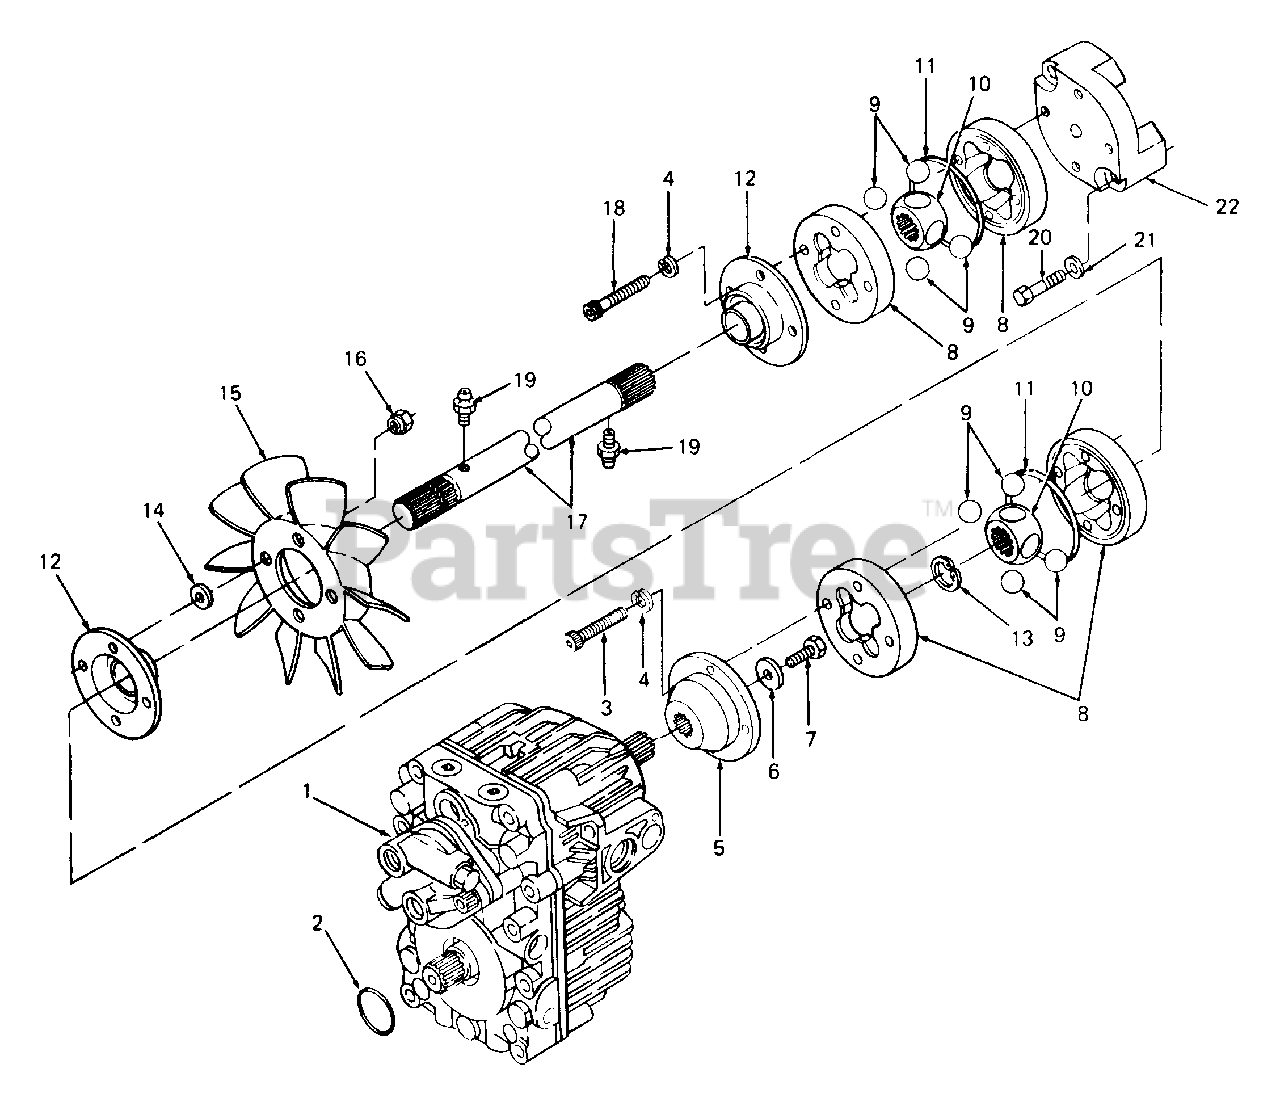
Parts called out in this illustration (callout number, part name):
1	Pump, Hydrostatic
2	O-Ring, 2.75 ID X .103 Dia
3	Screw, Socket Hd Cap, 1/4-20 X 2.0 Lg
4	Washer, Lock, 1/4
5	Adapter, Pump
6	Washer, Bell, .265 X .75 X .062 Thk
7	Bolt, Hex Patch, M6-1.0 X 20 MM Lg GR 10.9
8	Coupling, Drive w/O-Ring Groove
9	Ball, Steel, 5/8 Dia Chrome
10	Hub, Drive
11	O-Ring, 2.489 X .070
12	Boot, Coupling
13	Ring, Snap
14	Washer, Flat, .25 X .62 X .052 Thk
15	Fan, 10 Blade Hydro
16	Nut, Fan, 1/4-20
17	Shaft, Drive, 20.38 Lg
18	Screw, Socket Hd Cap, 1/4-20 X 1.75 Lg
19	Fitting, Grease
20	Bolt, Hex Patch, M8-1.25 X 50 MM
21	Washer, Flat, .312 X .750 X .119 Thk 2
22	Adapter, Drive Shaft
